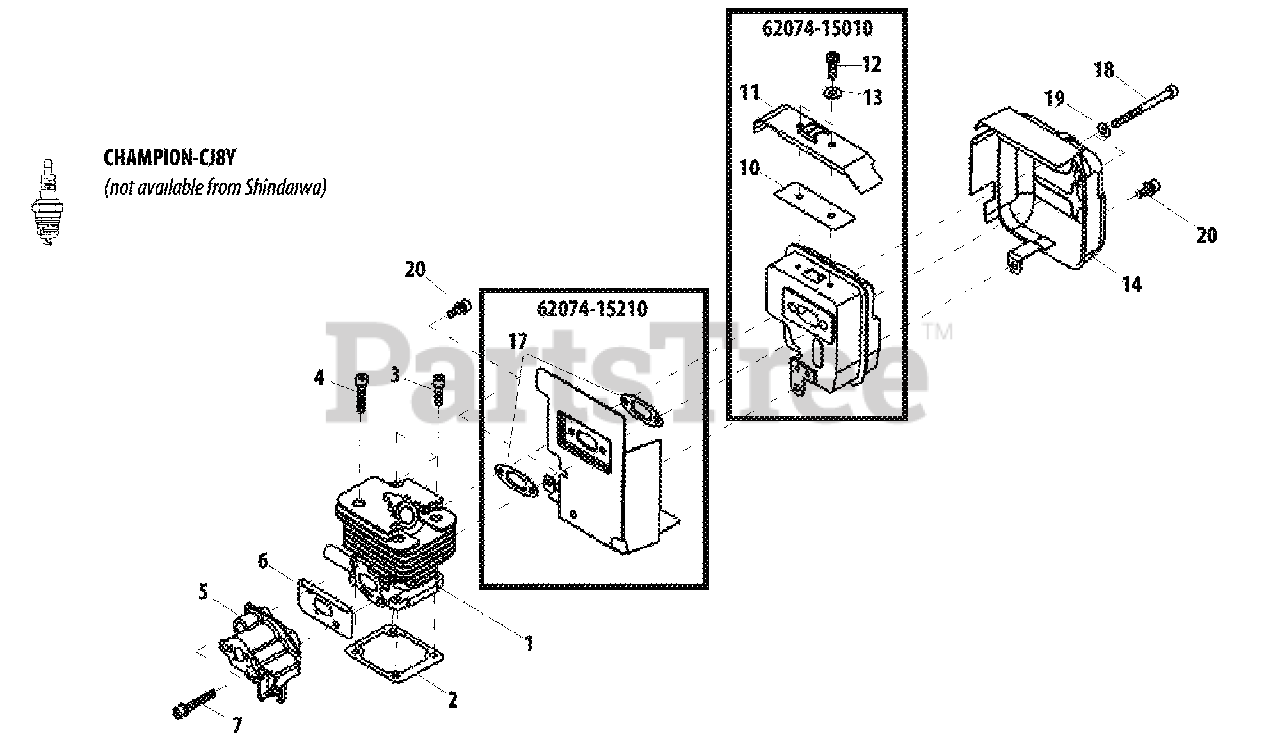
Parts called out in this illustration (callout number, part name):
1	CYLINDER
2	GASKET, CYLINDER
3	BOLT M5×16
4	BOLT
5	INSULATOR
6	GASKET
7	BOLT SS M5×30
10	SCREEN
11	TAIL PLATE
12	SCREW M4×6
13	WASHER 4 MM
14	COVER, MUFFLER
17	GASKET
18	BOLT M5×60
19	WASHER SS 5 MM
20	BOLT M5×12
6207415010	MUFFLER ASSY
6207415210	GASKET
